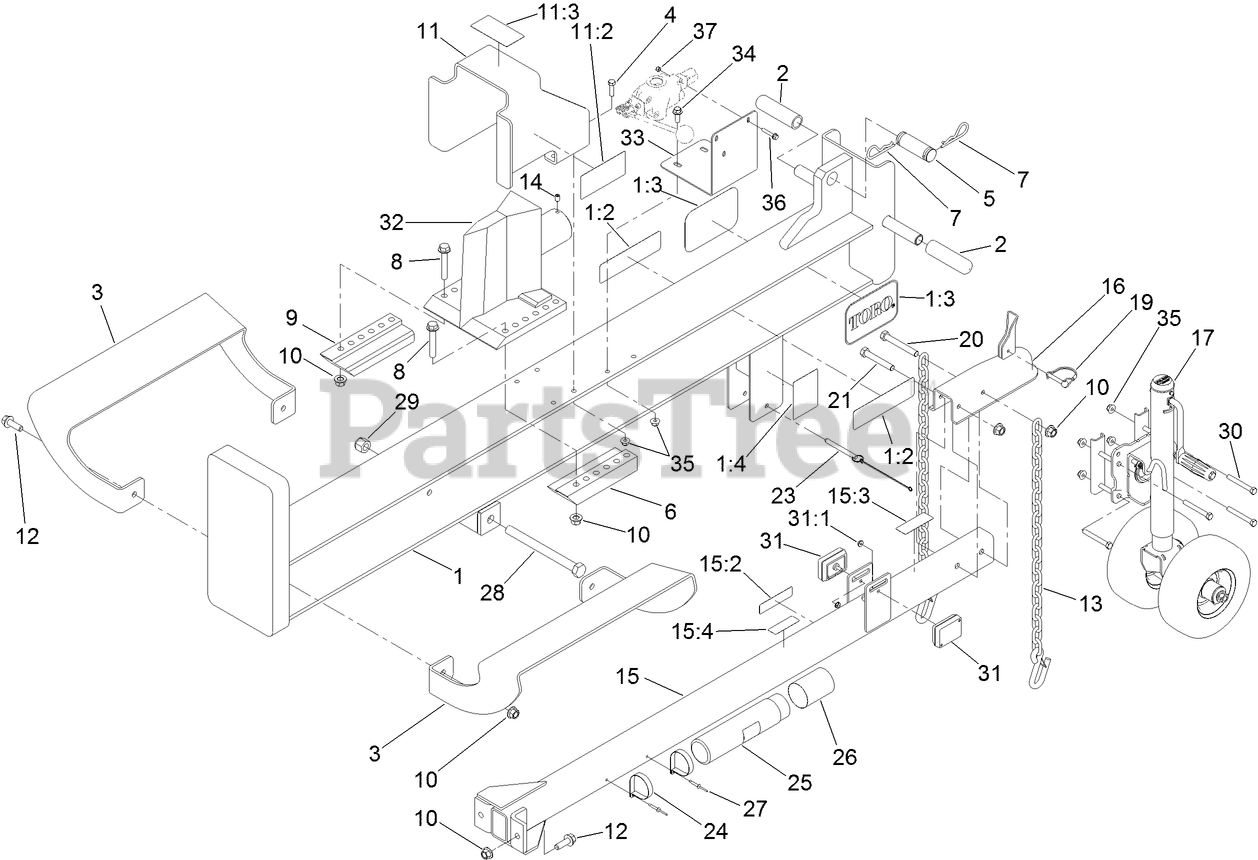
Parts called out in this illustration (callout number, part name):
1	BEAM ASM
1:2	DECAL-LS922
1:3	DECAL
1:4	DECAL-WARNING, PIN
2	GRIP-HANDLE
3	PLATE-CATCH
4	SCREW-HH
5	PIN-PIVOT
6	BAR-SLIDE, LH
7	PIN-HAIR
8	SCREW-HF
9	BAR-SLIDE, RH
10	NUT-LOCK
11	DISLODGER BRACKET ASM
11:2	DECAL-CAUTION, DANGEROUS AREA
11:3	DECAL-WARNING, PINCH POINT
12	SCREW-HHF
13	CHAIN-SAFETY, TRAILER
14	SCREW-SET
15	TUBE ASM
15:2	DECAL-ARRESTER, SPARK
15:3	DECAL-CAUTION
15:4	DECAL-WARNING, PINCH POINT
16	RECEIVER-HITCH, BALL
17	JACK ASM
19	PIN-LOCK
20	SCREW-HH
21	SCREW-HH
24	CLAMP-R
25	TUBE-MANUAL
26	CAP-HOUSING
27	RIVET-BLIND
28	BOLT-HH
29	NUT-LOCK, NI
30	SCREW-HH
31	LAMP-MARKER, FRONT SIDE
31:1	NUT-KEPS
32	WEDGE ASM
33	BRACKET-VALVE
34	SCREW-HHF
35	NUT-HF, NI
36	SCREW-HHF
37	NUT-LOCK, NI
